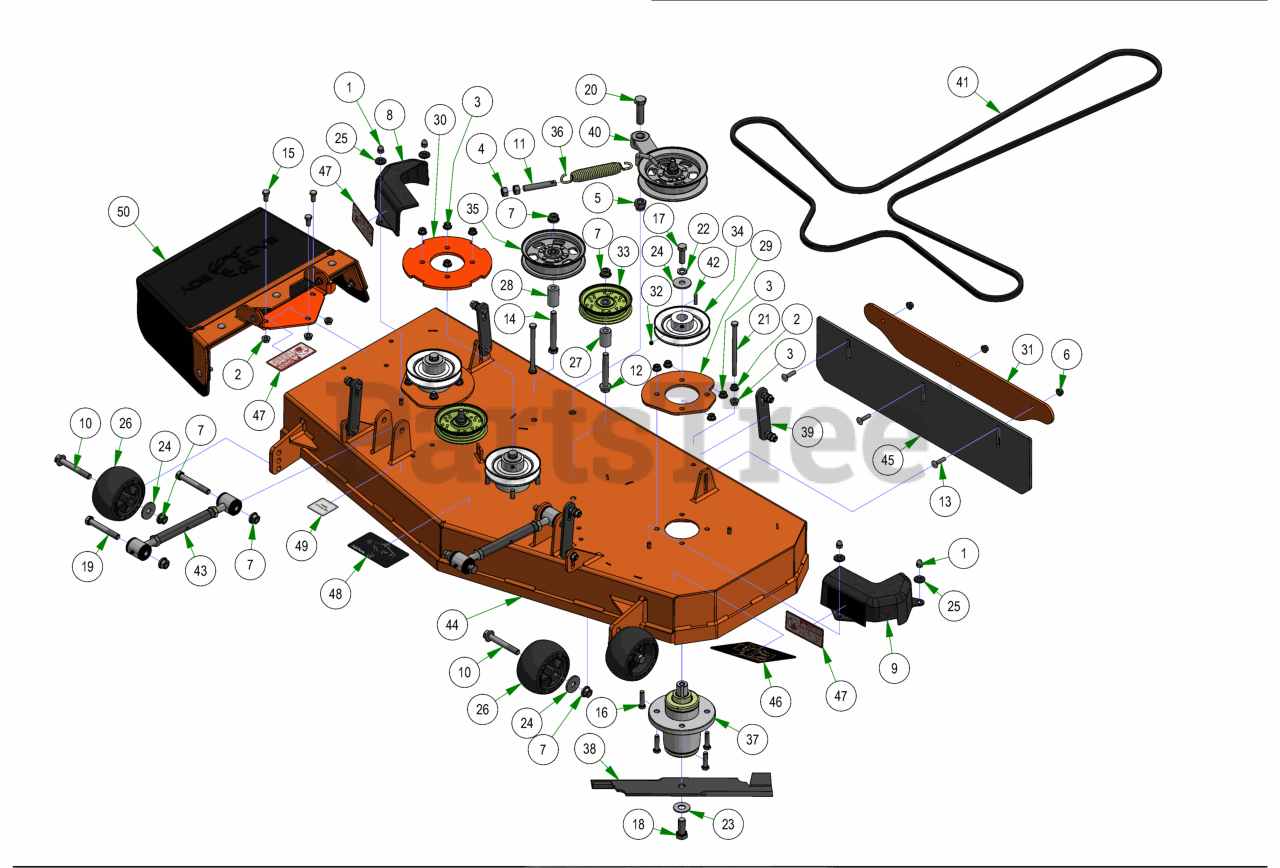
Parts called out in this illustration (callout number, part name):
1	5/16-18 ACORN NUT HIGH-CROWN ZC
2	3/8-16 HEX SERRATED FLANGE NUT HARD/ZINC
3	3/8-16 NYLON INSERT FLANGE LOCKNUT (GR.F) ZINC
4	1/2-13 HEX NUT ZINC
5	5/8-11 NYLON INSERT LOCKNUT ZINC
6	5/16-18 NYLON INSERT FLANGE LOCKNUT ZINC
7	1/2-13 NYLON INSERT FLANGE LOCKNUT ZINC
8	Pulley Cover Chute Side
9	Pulley Cover Non-Chute Side
10	1/2-13 X 90MM HEX FLANGE BOLT W/SHOULDER (GR.8) ZINC
11	All Thread
12	1/2-13 X 3-1/2 HEX FLANGE BOLT (GR.8) ZINC
13	5/16-18 X 1-1/4 CARRIAGE BOLT ZINC
14	1/2-13 X 4 HEX CAP SCREW (GR.8) ZINC YELLOW
15	3/8-16 X 3/4 HEX CAP SCREW (GR.5) ZINC
16	3/8-16 X 1-1/2 HEX CAP SCREW (GR.5) ZINC
17	1/2-20 X 1-1/2 HEX CAP SCREW (GR.5) ZINC
18	5/8-18 X 1-1/2 HEX CAP SCREW (GR.8) ZINC YELLOW
19	1/2-13 X 3-1/2 HEX CAP SCREW (GR.5) ZINC
20	5/8-11 X 2-1/4 HEX CAP SCREW (GR.5) ZINC
21	3/8-16 X 5-1/2 HEX CAP SCREW (GR.5) ZINC
22	1/2 SPLIT LOCKWASHER (GR.8) ZINC/YELLOW
23	5/8 USS FLAT WASHER (1-3/4" OD) GR.8 ZINC YELLOW
24	1/2 BELLEVILLE WASHER (1-5/8 OD X .140 THK) ZINC
25	.360 ID X .983 OD X .120 THICK FLAT WASHER NYLON BLACK
26	Deck Wheel
27	.502 ID X .750 OD X 1.500 Long Spacer
28	1 3/4" Pulley Spacer
29	42&48 Deck Spindle Support Plate
30	Deck Spindle Support Plate
31	2023 4" & 5" Stripping Kit Plate
32	5/16-24 X 1/4 SOCKET SET SCREW (CUP PT) PLAIN
33	4 3/4 Idler Pulley - ABFI-76
34	5" Spindle Deck Pulley
35	5-3/4 Idler Pulley
36	Deck Idler Spring
37	OUTLAW SPINDLE ASSEMBLY
38	48" ZT/Mav/Compact Outlaw Blade with Fusion
39	Deck Hanger Assembly
40	Maverick HD & Down Deck Idler Assembly
41	B147 Deck Belt
42	1/4 X 1 SQ MACHINERY KEY 1018 STL PLN
43	2018 Maverick Turnbuckle (Top Link)
44	2025 48" x 5" Deck
45	2023 ZT Stripping Kit Rubber
46	48" Grip Deck Decal
47	Danger Decal-Spindle/Discharge
48	Deck Belt Route Decal
49	Deck Impact Patent Decal 9591803
50	ZT Chute Assembly
